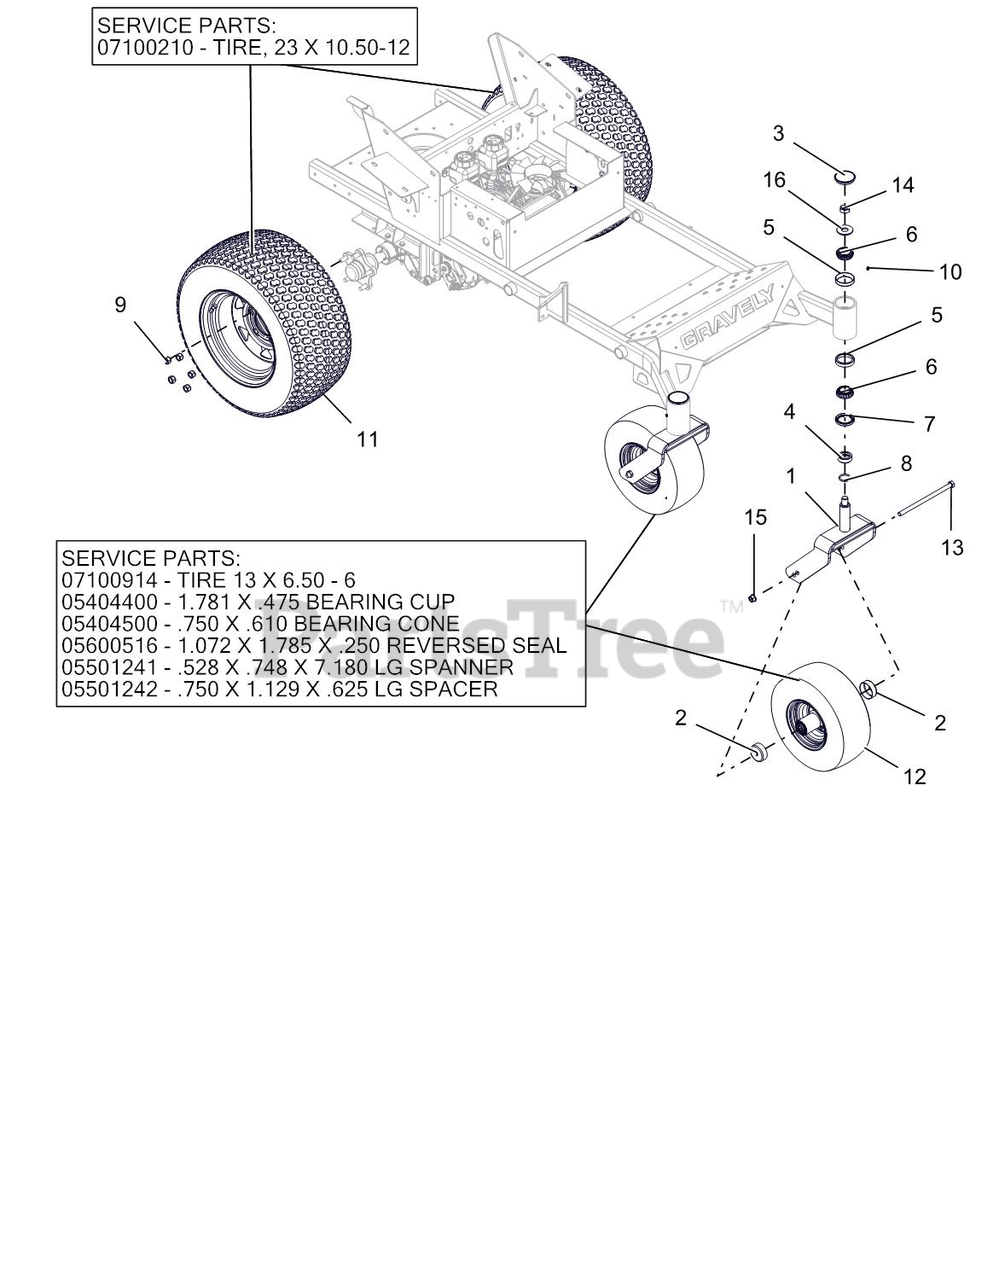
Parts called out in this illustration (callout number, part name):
1	WMT, CASTER FORK - RED
2	SHIELD, WHEEL BEARING
3	CAP, DUST
4	SPCR, FRONT CASTER FORK
5	BRG, CUP 2.328 X .465
6	BRG, CONE 1.250 X .660
7	SEAL, OIL 1.75 X 2.332 X .312
8	O-RING, .139 W X 1.234 ID
9	NUT, LUG .500-13
10	FITTING, .250-28 FLUSH MOUNT GREASE
11	TIRE, 23 X 10.50-12
11	ASSM TIRE\WHEEL, 23 X 10.50 - 12
12	TIRE 1 X 6.50-6
12	1.781 X .475 BEARING CUP
12	.750 X .610 BEARING CONE
12	1.072 X 1.785 X .250 REVERSED SEAL
12	.528 X .748 X 7.180 LG SPANNER
12	.750 X 1.129 X .625 LG SPACER
12	ASSM TIRE\WHEEL, 13 X 6.50-6 SMOOTH
13	BOLT, HEX 0.5-13X9 GR5
14	NUT-LK-TOP-JAM .75-16 YWZC
15	NUT, LK-TOP-FLG .50-13 YWZC
16	WSHR-FL-STL.812X2.00X.148YWZC
